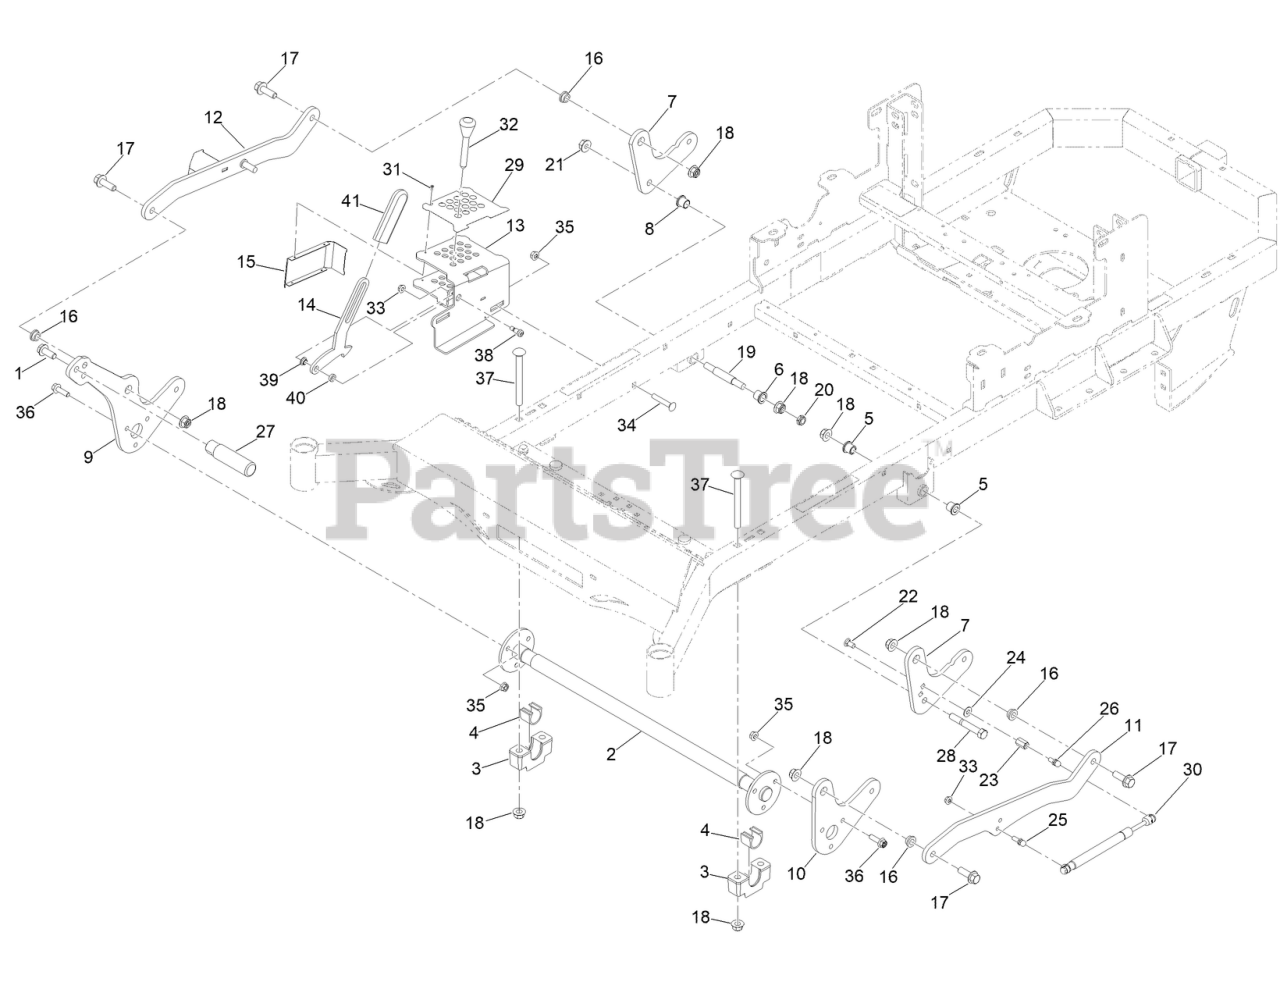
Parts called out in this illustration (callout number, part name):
1	1/2-13X1.25IN HEX FLANGE BOLT (GR.8) YZ
2	DECKLIFT ASM-FRONT
3	SUPPORT-BEARING HOUSING
4	BEARING-CROSS SHAFT, FRONT
5	BUSHING-FLANGE
6	BUSHING-FLANGE
7	(RZ REAR HOC HANGER)
8	ARM-DECKLIFT REAR (3/8")
9	LEVER-LIFT
10	PLATE-DECKLIFT, ARM LH
11	LINK-HOC(LEFT SIDE)
12	LINK ASM-HOC(RIGHT SIDE WELDED)
13	BRACKET-HOC ASM [BLK-TXT]
14	PLATE-TRANSPORT LOCK
15	COVER-HOC
16	1/2IN ID X 3/4IN OD X 3/8IN FLANGE BUSH
17	SCREW-HHF
18	1/2-13 HEX FLANGE 2-WAY REV CNTR L/NYZ
19	RR DECK HEIGHT BOLT (MACHINED)
20	NUT-HEX
21	NUT-HHF
22	3/8 X 3/4IN GR 8 CARR BOLT ZINC
23	HEX COUPLING NUT - REDUCER (3/8" TO 5/16
24	WASHER-FLAT
25	5/16-18X1.286 DAMPER BALL STUD (.562 TL)
26	5/16-18X1.286 DAMPER BALL STUD (.562 TL)
28	1/2-13 X 3-1/2 HEX C/S GR 5 ZINC YELLOW
29	DECAL-HEIGHT OF CUT
30	DECK ASSIST GAS SPRING
31	RIVET
32	MAGNETIC PIN FOR STAND ON MWR
34	SCREW-CARR
36	SCREW-HHF
37	SCREW-CARR
38	3/8 X 1/2 SOCKET SHOULDER BOLT YZ
39	BUSHING-FLANGE
40	WASHER-PLAIN
41	STAND UP MWR BRAKE ARM GRIP
